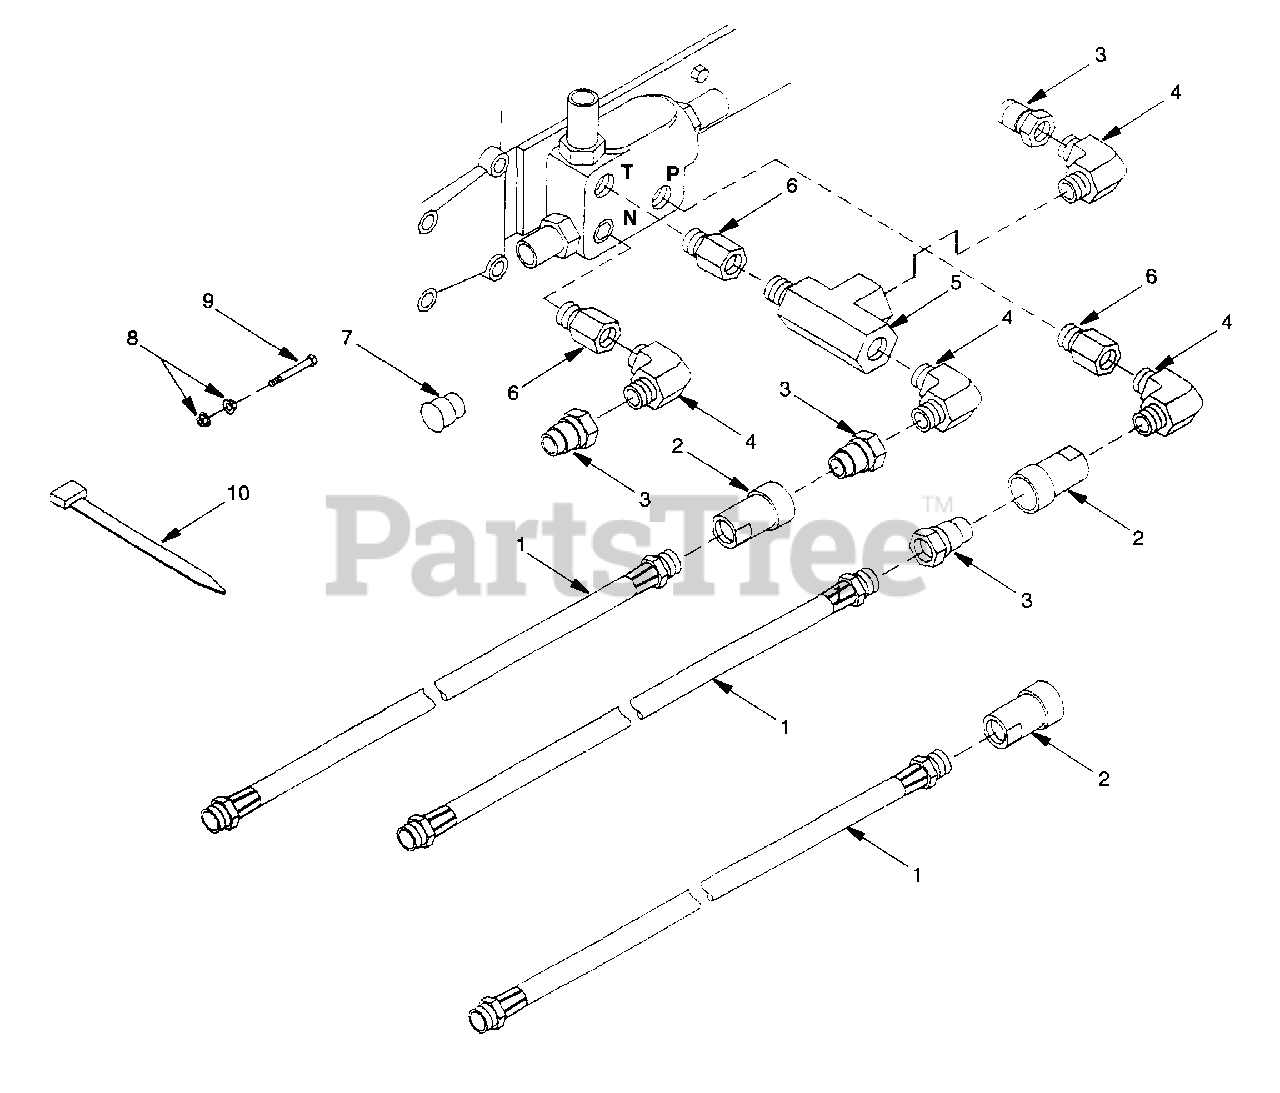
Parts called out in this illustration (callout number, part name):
1	Hose, 3/8 112 3/4 SAE M 3/8 NPT M
2	Quick Coupler, 3/8 NPT Female
3	Quick Coupling, 3/8 NPT Male
4	Elbow, Male 3/8 NPT x 90°.
5	Run Tee, 3/8 NPT
6	Adapter, 3/8 BSTP Male 3/8 NPT
7	Dust Plug - Blue
8	Flanged Locknut, 1/4 NC
9	Hex Hd Cap Screw, 1/4 NC x 4 GR5
10	Hydraulic Hose Tie, 7 Long
